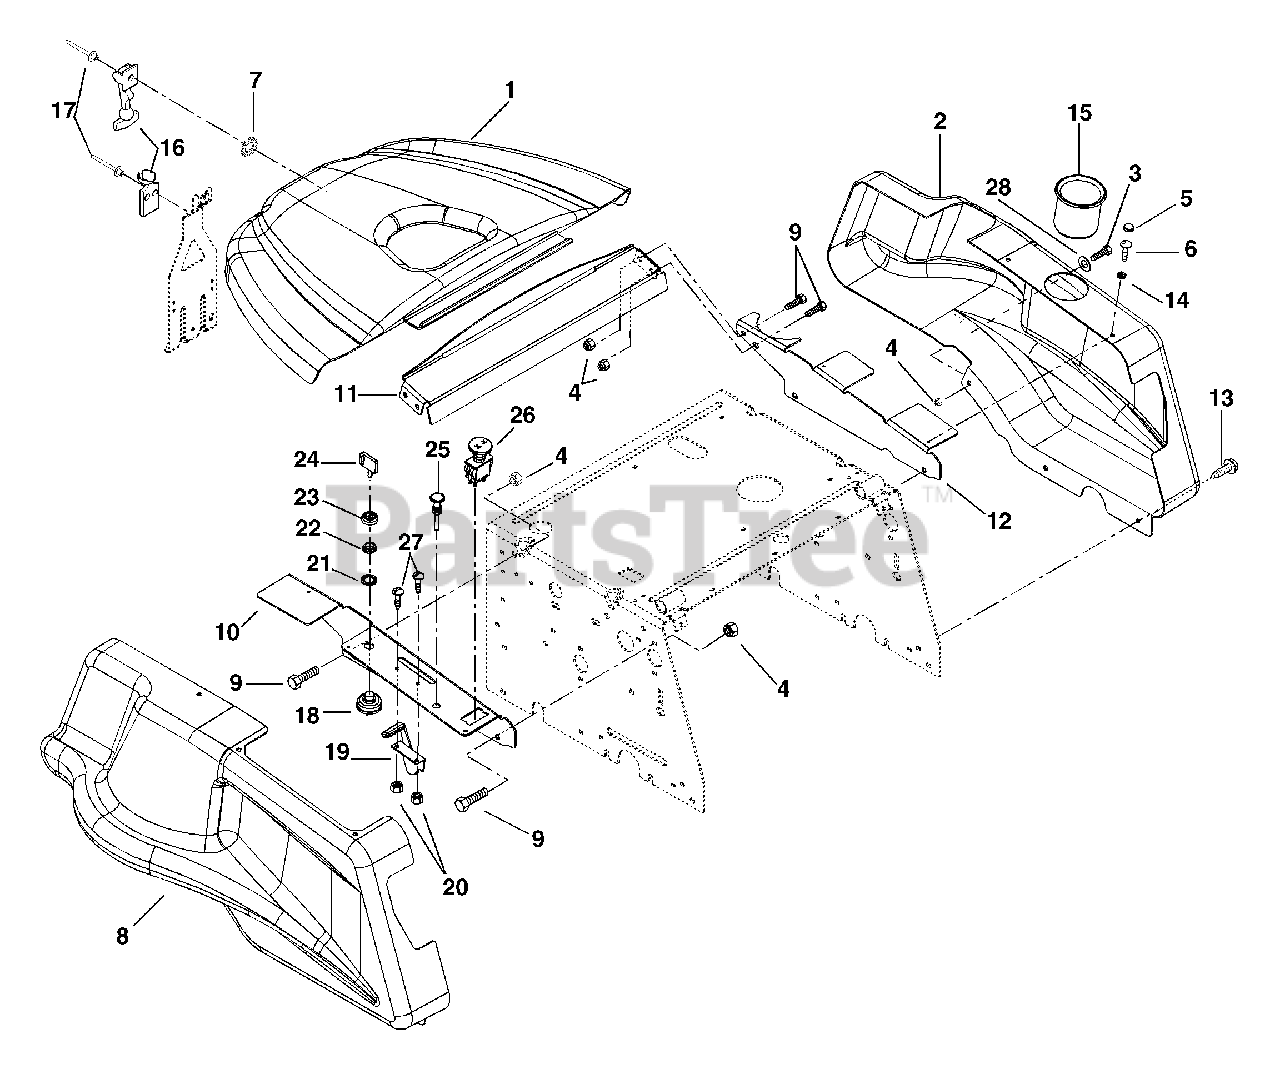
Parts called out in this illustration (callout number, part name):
1	Shroud, Top
2	Shroud, Side Left Hand
3	Bolt-Hex .31-18 x .75 Grade 5
4	Nut-Locking-Nylon .312-18
5	Snap-Cap Top Cap
6	Screw-Tapping .10-24 x .50
7	Rivet-Burr .125 x .505 x.048
8	Shroud-Side Right Hand
9	Bolt-Hex .312-18 x .75 Grade 5
10	Bracket-Control
11	Bracket-Hood
12	Bracket-Fuel Tank
13	Screw-Tapping .312-18 x .75 Hex Washer Head
14	Snap-Cap Washer
15	Cupholder
16	Latch, Flexible
17	Rivet-Pop
18	Key Switch
19	Cable-Throttle
20	Nut-Locking-Nylon 10-24
21	Washer-Lock-Internal
22	Nut-Ignition
23	Cap-Ignition Switch
24	Key-Ignition
24	Key Chain
25	Cable-Choke
25	Plug-Hole Plastic .44
26	Switch-Clutch
27	Screw-Machine 10-24 x .50
28	Washer-Flat-Steel .344 x .688 x .065
